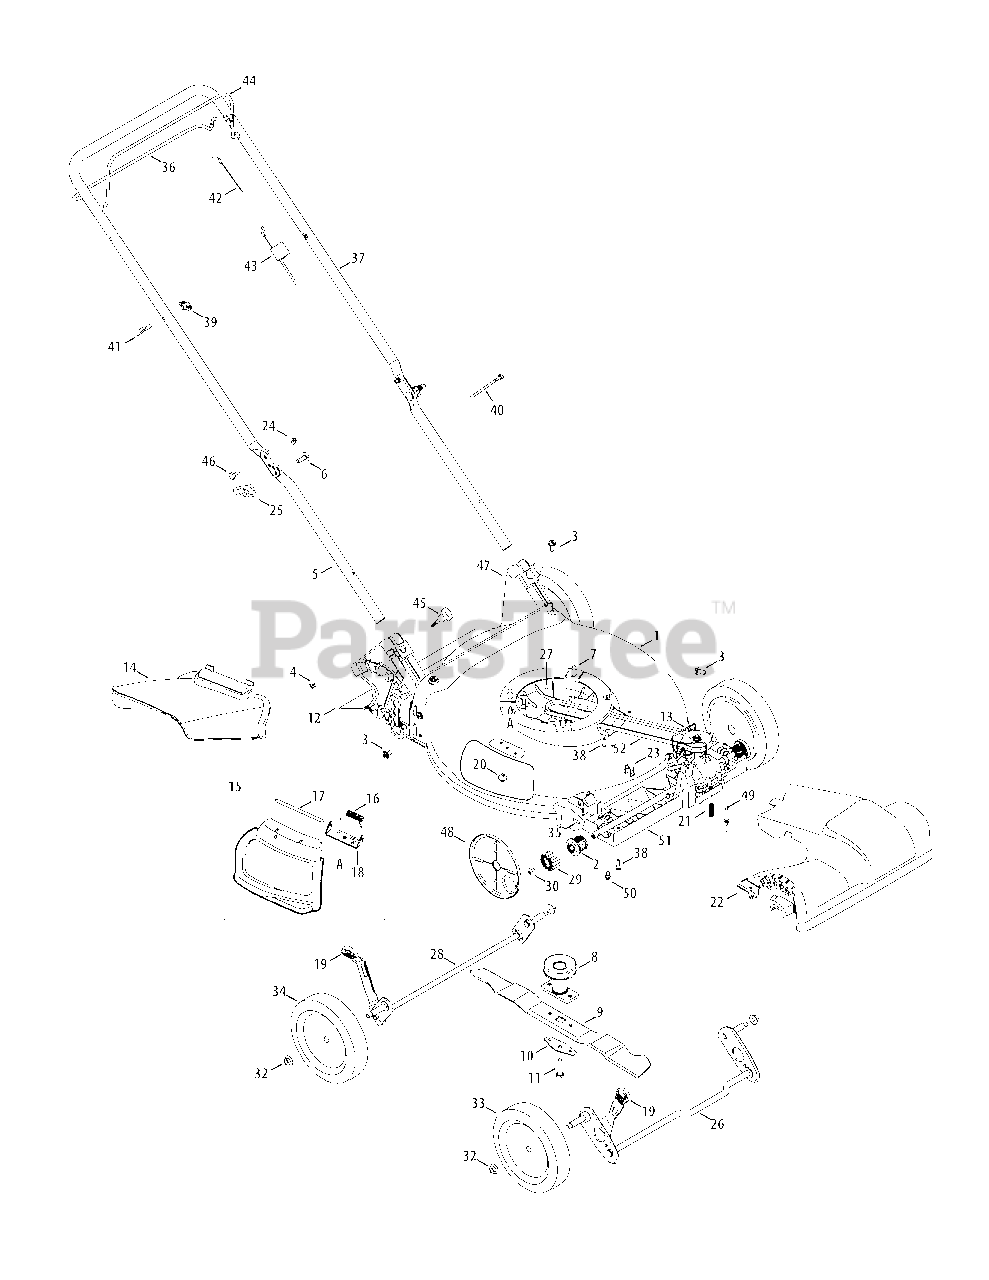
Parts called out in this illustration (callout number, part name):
1	Deck , 21"
2	Bearing Assembly
3	Screw, 5/16-14 x .750
4	Nut, Sq., 1/4-20
5	Lower Handle
6	Carriage Screw ,5/16-18
7	Screw, 3/8-16 x 1.00
8	Blade Adapter
9	Mulching Blade
10	Blade Bell Support
11	Screw, 3/8-24 x 1.50
12	Trailing Shield
13	Transmission Wire
14	Side Discharge Chute
15	Mulch Plug (Incl. 16-18)
16	Torsion Spring
17	Hinge Pin
18	Chute Deflector Bracket
19	Adjustment Lever Knob
20	Screw, 1/4-20 x .500
21	Compression Spring
23	Front Axle Clip
24	Nut, Flange Lock, 1/4-20
25	Wing Knob
26	Front Axle Assembly
27	Engine Baffle
28	Rear Axle Assembly
29	Spur Gear, 14T - RH
29	Spur Gear, 14T - LH
30	Screw, 1/4-20 x .390
32	Flange Lock Nut, 3/8-16
33	Front Wheel
34	Rear Wheel
35	Dowel Pin
36	Drive Control
37	Upper Handle
38	Screw, 1/4-15 x .750
40	Cable Tie
41	Rope Guide
42	Control Cable
43	Drive Cable
44	Blade Control
45	Wing Nut
46	Sldr. Screw, .375 x .126 x 1/4-20
47	Rear Baffle
48	Wheel Dust Cover
49	Spring Body
50	Scr., Shldr., 1/4-20 x .50
51	Lower Tray
